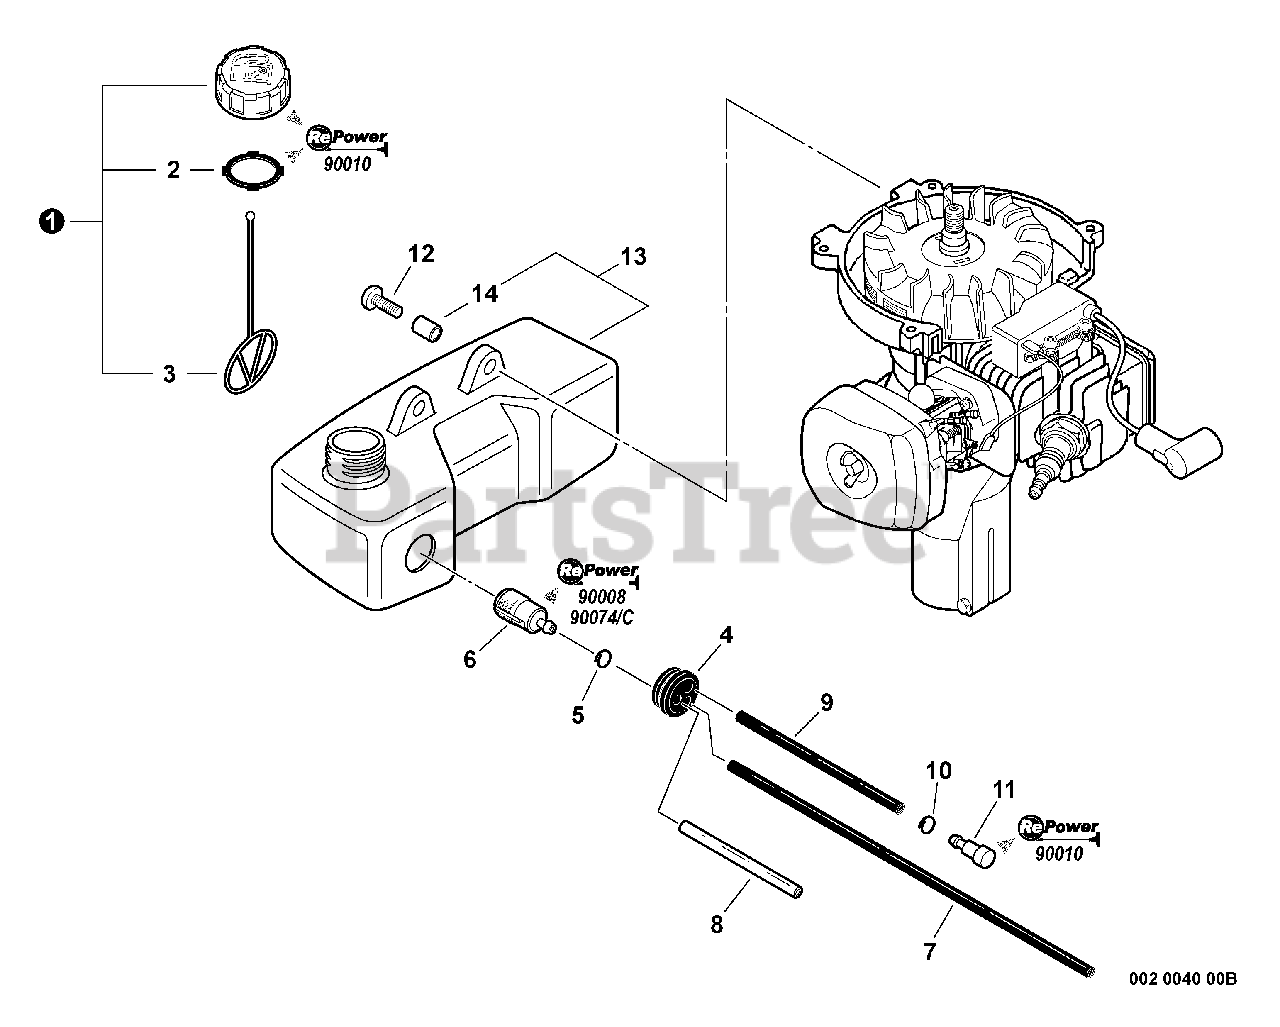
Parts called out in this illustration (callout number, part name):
1	CAP ASSY - ORANGE
2	GASKET, CAP
3	CONNECTOR, CAP
4	GROMMET
5	CLIP - 6
6	FILTER, FUEL
7	PIPE - 3X5X210 -- BLACK
8	PIPE - 3X6X50 -- CLEAR
9	PIPE - 3X5X70 -- BLACK
10	CLIP - 5.5
11	VENT, FUEL TANK
12	SCREW - 5X15
13	FUEL TANK ASSY
15	RePower TUNE-UP KIT
16	RePower FILTER KIT
17	Repower CAP AND VENT KIT
